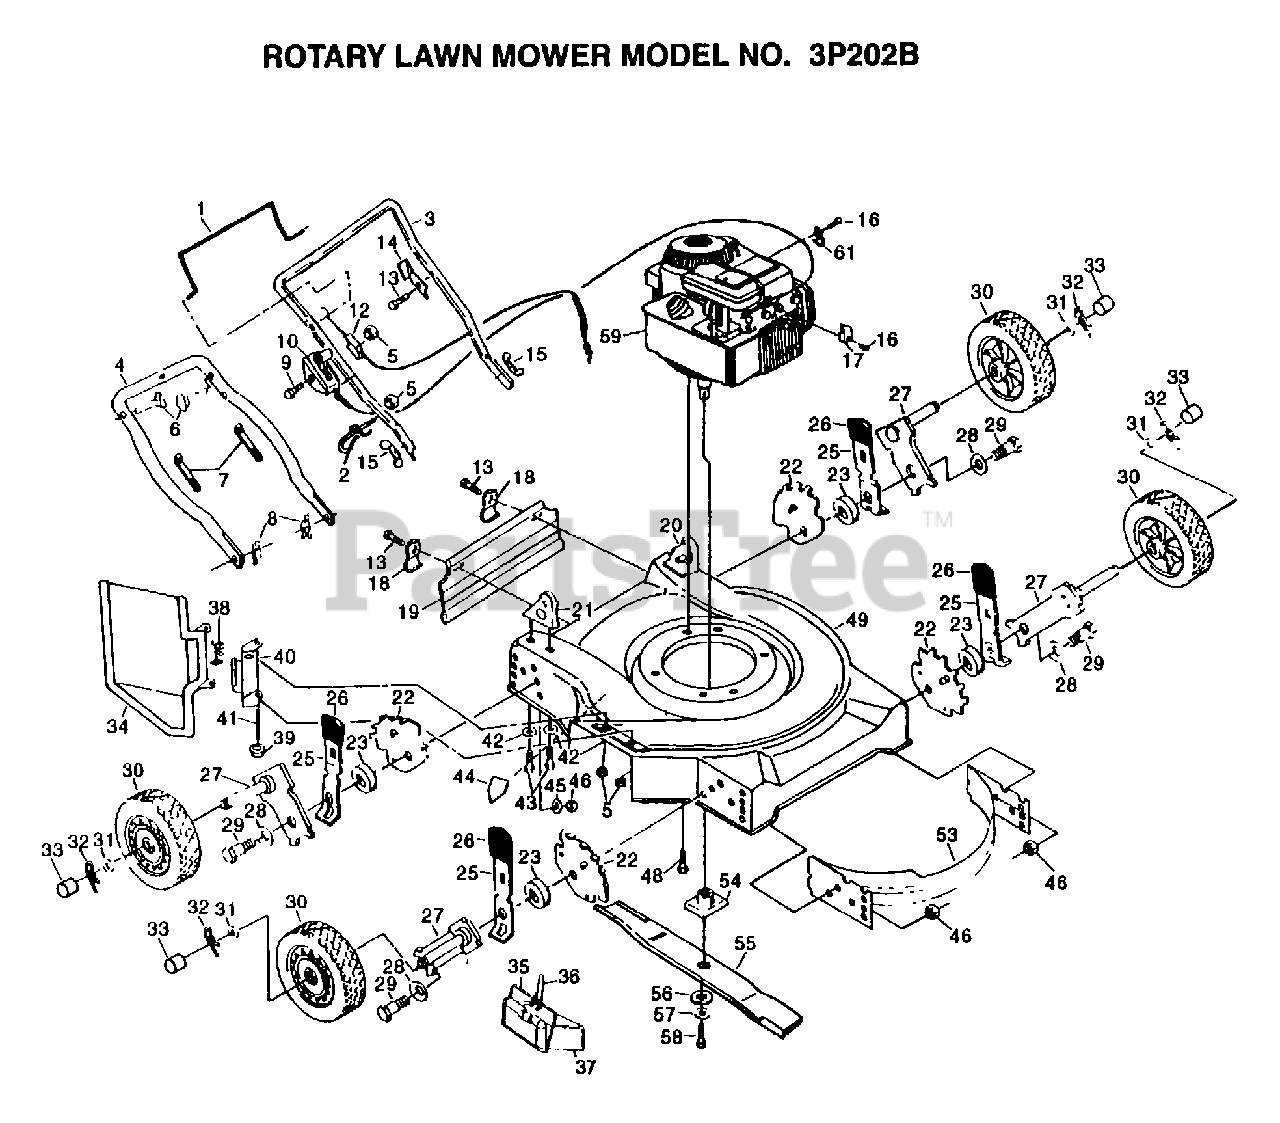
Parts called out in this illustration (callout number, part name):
1	CONTROL BAR PM
2	ROPE GUIDE
6	BOLT.HANDLE.LM
8	HAIRPIN COTTER
9	SCREW.HXHD.WASH.
10	CONTROL THROTTLE
12	"CABLE,ENG ZONE CO"
13	TAPPING SCREW
14	"BRKT,UPSTOP"
15	"NUT,WING PM"
16	SCREW PM
17	CABLE CLAMP
18	"BRKT,DEFL PM"
19	SKIRT.REAR.FGD.22
22	BRACKET.WHL.ADJ.9
25	SPRING SELECTOR
26	KNOB PM
27	AXLE ARM
28	"WASHER, BELLEVIL."
29	BOLT SHLD 3/8-16
30	WHEEL.ASM
31	WASHER
32	RETAINER CLIP PM
33	HUB CAP-PLASTIC
34	GUARD.DISCH.22SD.
35	BAIL.PLUG.MUL.22.
36	LATCH.PLUG.22SD
40	BRACKET.HINGE.W/F
41	ROD.HINGE.COMBI-C
42	STEEL WASHER
43	SCREW
44	DECAL HYT
46	LOCKNUT PM
48	SCREW
49	KIT.HSG.22SD.PUSH
53	BAFFLE.FRT/REAR
54	BLADE ADAPTOR
55	"BLADE.MULCH.22"""
56	"WASHER,HARDEN"
57	LOCKWASHER
58	SCREW
61	GUIDE CLIP PM
